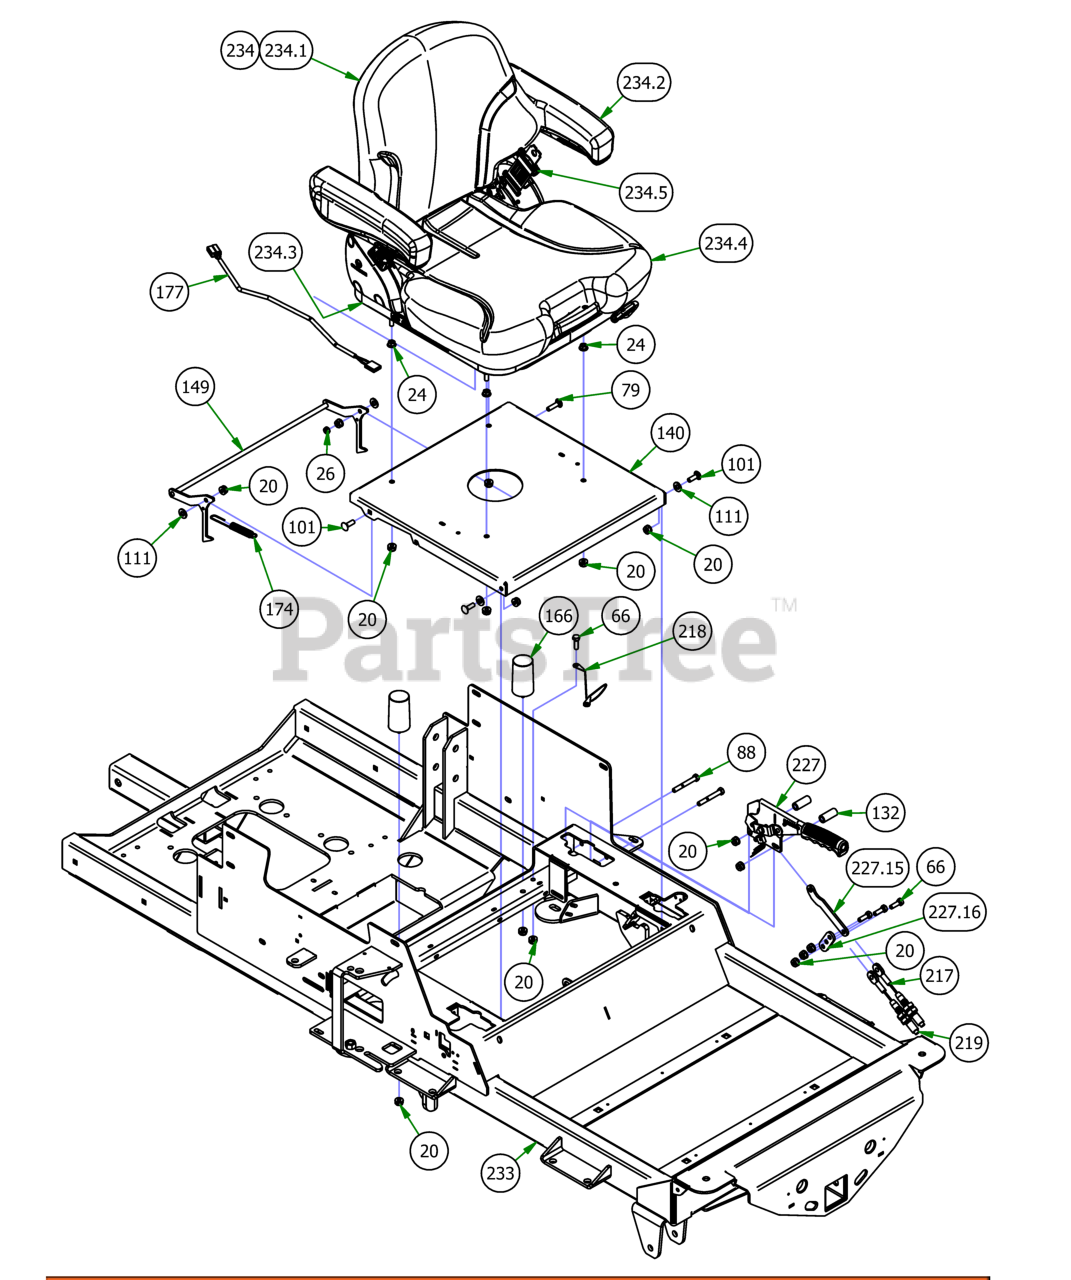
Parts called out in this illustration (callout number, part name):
20	5/16-18 Nylon Flange Nut
24	5/16" Flange Nut
26	5/16-18 Nylock Jam Nut 1/2 Nut
66	5/16" x 1" Bolt
79	5/16" x 1 1/4" Carriage Bolt
88	5/16" x 2 1/2" Bolt
101	5/16" x 1" Carriage Bolt
111	.360 ID Plastic Washer
132	2019 Outlaw Brake Handle Spacer .625 x 1.5
140	2019 Outlaw Seat Plate
149	Seat Latch Rod Assembly
166	2019 Bad Boy X Cylindrical Seat Mount
174	Brake Spring
177	Seat Switch Adapter
217	2019 Short Brake Cable-Suspension Models
218	Seat Cable
219	2019 Long Brake Cable-Renegade, Rogue
227	2019 Brake Handle Assembly
227.15	2019 Brake Load Balancer - Upper Tab
227.16	2019 Brake Load Balancer - Lower Tab
233	2019 Renegade Diesel Frame - Powdercoated
234	2019 Renegade Seat
234.1	Backrest Cushion
234.2	Arm Rest Kit
234.3	Slave & Adjuster
234.4	Seat Cushion
234.6	Seat Switch
